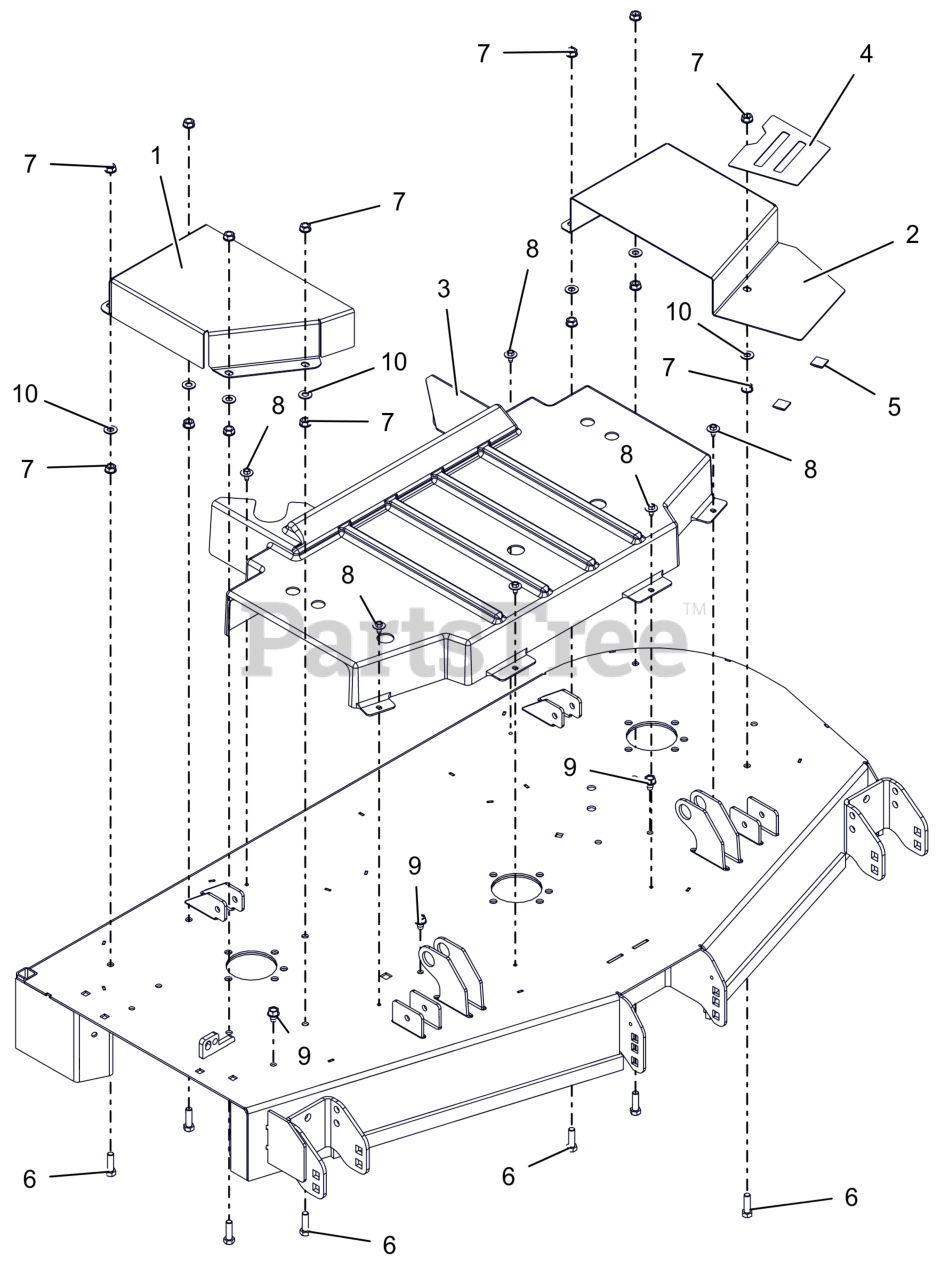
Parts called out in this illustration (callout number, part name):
1	GUARD,BELT 52" RIGHT CE
2	GUARD,BELT 52" LEFT CE
3	GUARD,CENTER,DECK SPINDLE CE
4	GRIP TAPE 52-60 BELT COVER
6	BLT, HEX .38-16X1.25 G5 ZCC
7	NUT, SPNLK-FLG .38-16 G5 ZCC
8	SCR, TAP .25-20X.50 LG HWH ZCC
9	SCR,TAP .375-16X.50 HWH TR ZCC
10	WSHR,FLT .406X.812X.065 ZCC
